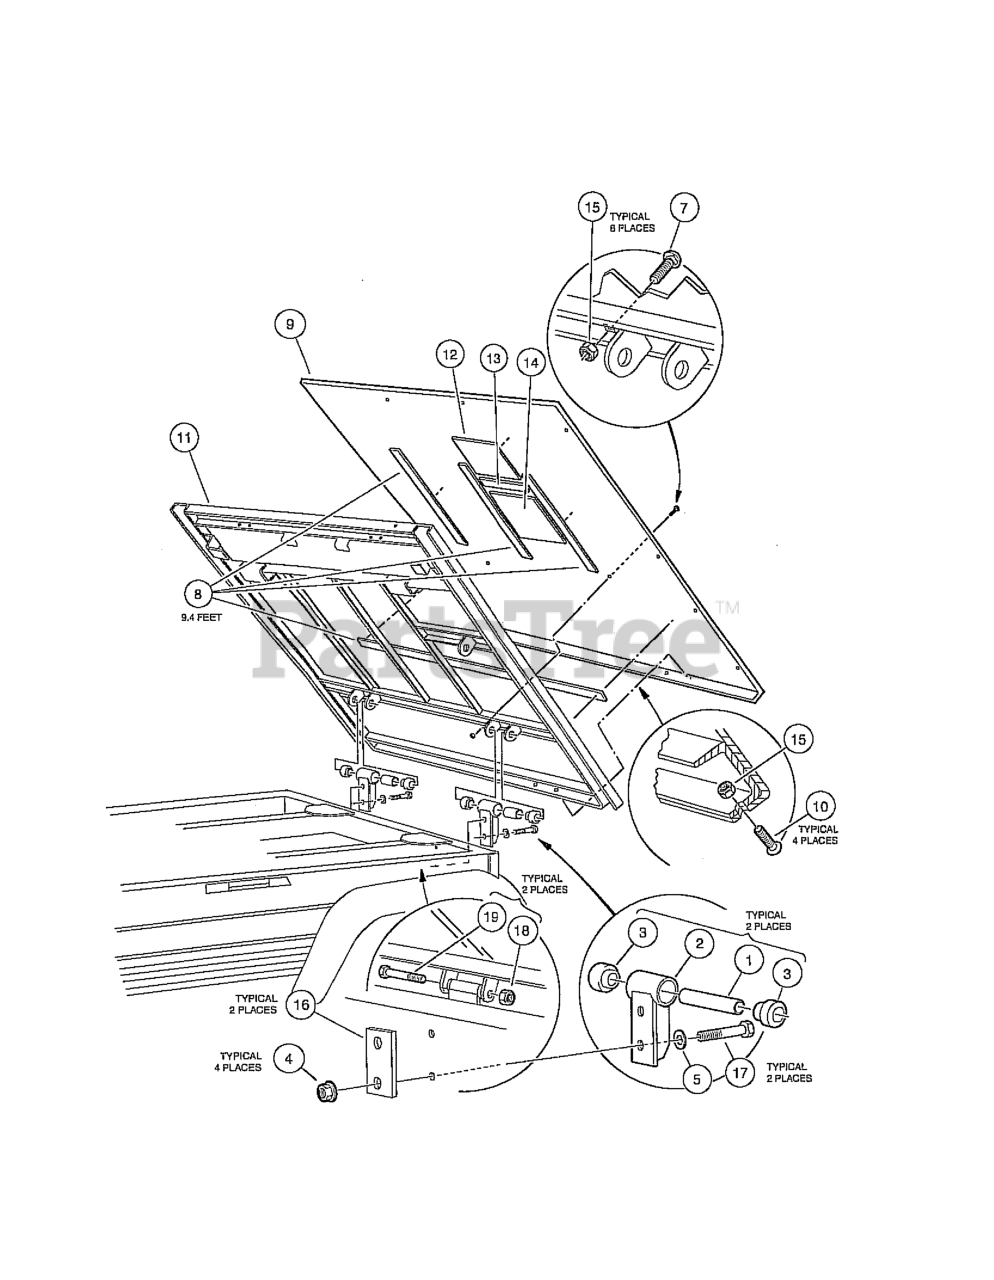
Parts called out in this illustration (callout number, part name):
1	BUSHING - STEEL (GAS CAR)
2	ASM, HINGE-TILT BED
3	BUSHING, URETHANE
4	LOCKNUT, 3/8-16 FLANGED DIMPLE
5	WASHER, 3/8 TYPE B HARD FLAT
6	TILT BED ASM AWD, ELEC LIFT
7	BOLT, 5/16-18 X 1.00 SQ.NECK
8	BOX INS.BULK
10	SCREW, 5/16-18 X .88 TRX TRUSS
13	FOAM, BARRIER, HEAT BED
14	FOAM, BARRIER, HEAT BED
15	LOCKNUT, 5/16-18 NYLON INSERT
16	PLATE, BACK
17	BOLT, 3/8-16 X 3.00 HEX HEAD
18	LOCKNUT, 3/8-16 HEX
19	SCREW, 3/8-16 X 3.375
